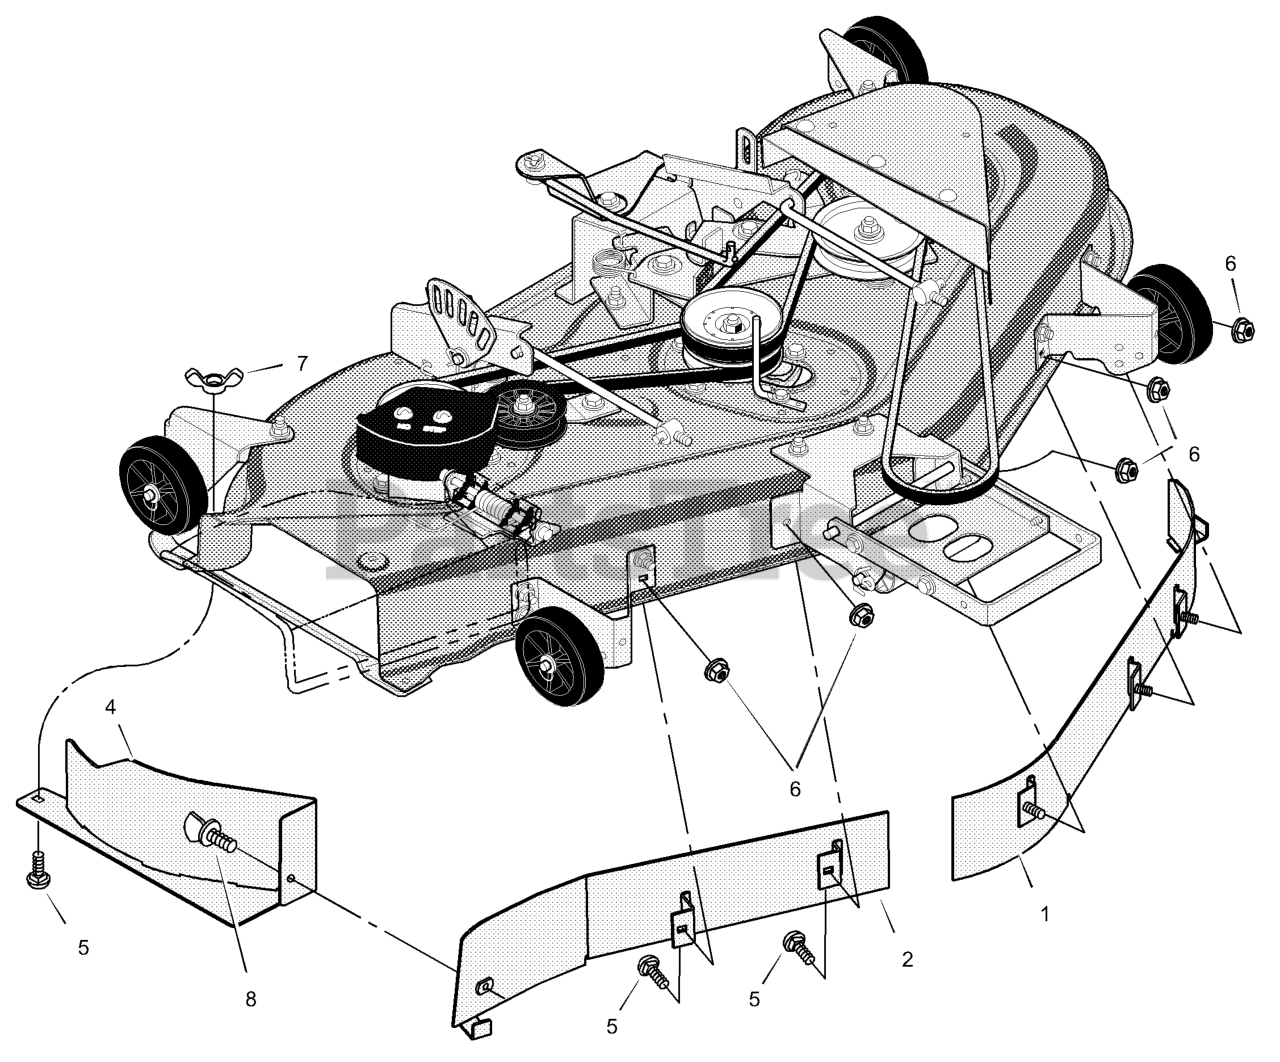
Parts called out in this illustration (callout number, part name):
1	Baffle, Left
2	Baffle, Right
4	Plate, Mulcher
5	Bolt, Carriage
6	Nut, Flange
7	Wingnut
8	Screw, Thumb
